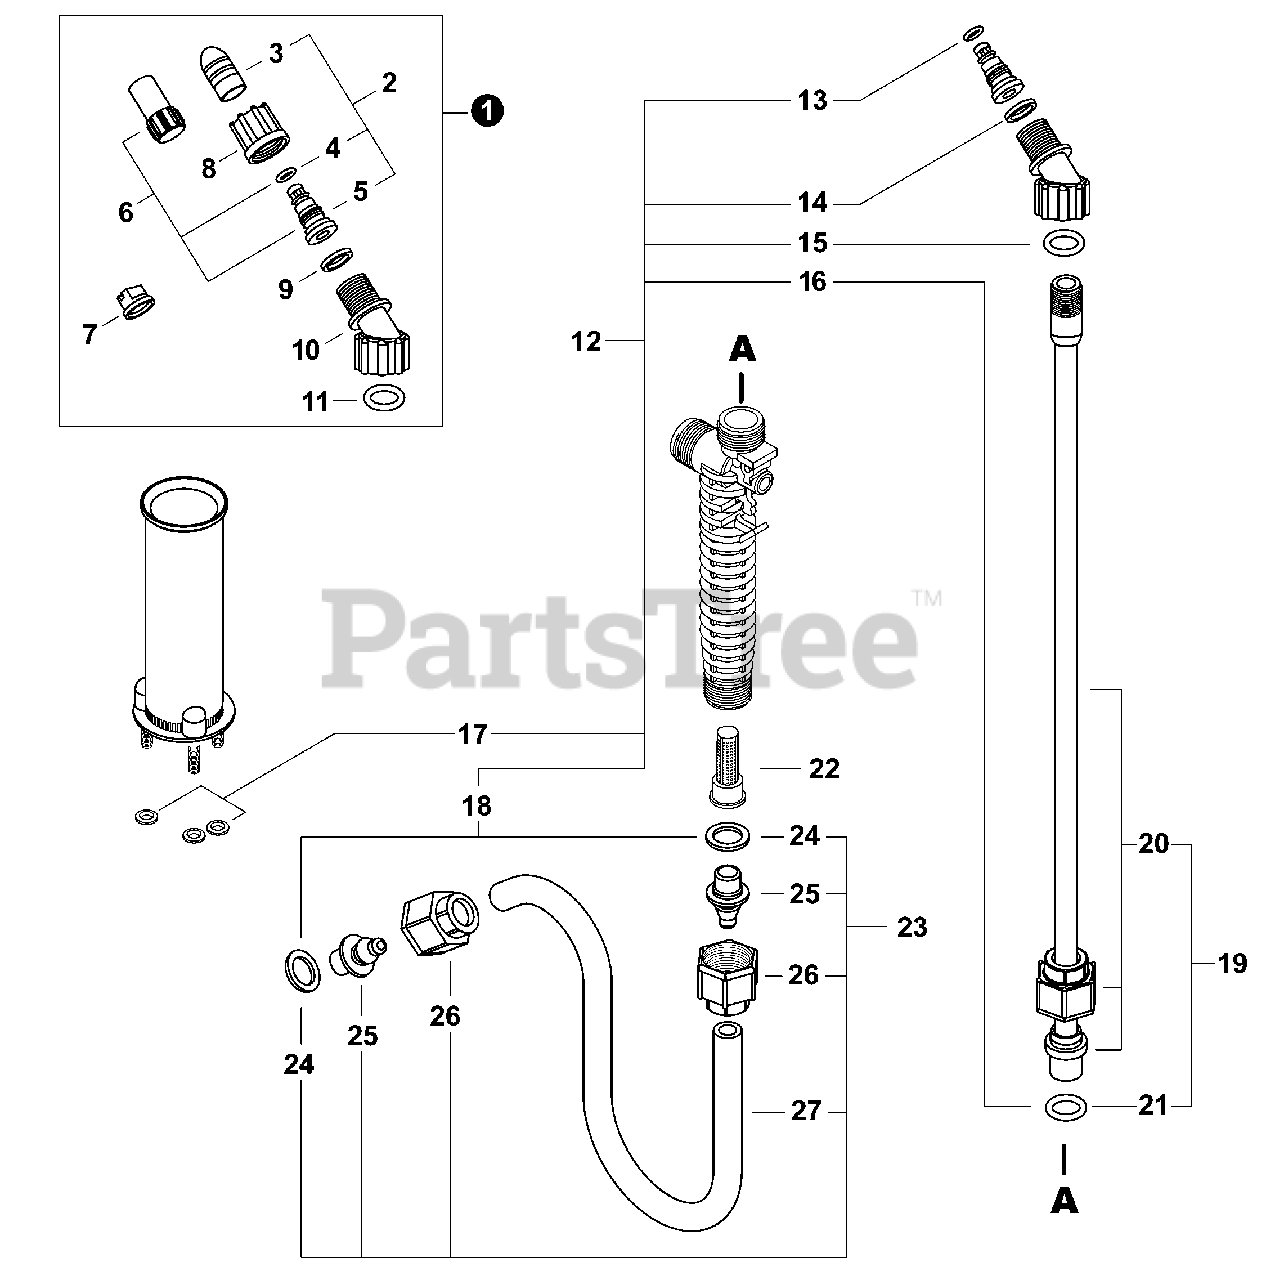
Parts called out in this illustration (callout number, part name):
1	NOZZLE KIT
2	NOZZLE KIT, BRASS
3	CAP, NOZZLE - BRASS
4	O-RING, NOZZLE
5	BODY, NOZZLE
6	NOZZLE KIT, PLASTIC
7	NOZZLE, FLAT FAN
8	NUT, NOZZLE
9	GASKET, NOZZLE
10	ELBOW, NOZZLE
11	O-RING, ELBOW
12	GASKET KIT, BPE
13	O-RING, NOZZLE
14	GASKET, NOZZLE
15	O-RING, ELBOW
17	GASKET, STUD
18	GASKET, ADAPTER
19	WAND ASSY, PLASTIC
20	WAND, PLASTIC
22	FILTER, SPRAY GUN
23	HOSE ASSY
24	GASKET, ADAPTER
25	ADAPTER, HOSE - BLACK
26	NUT, HOSE
